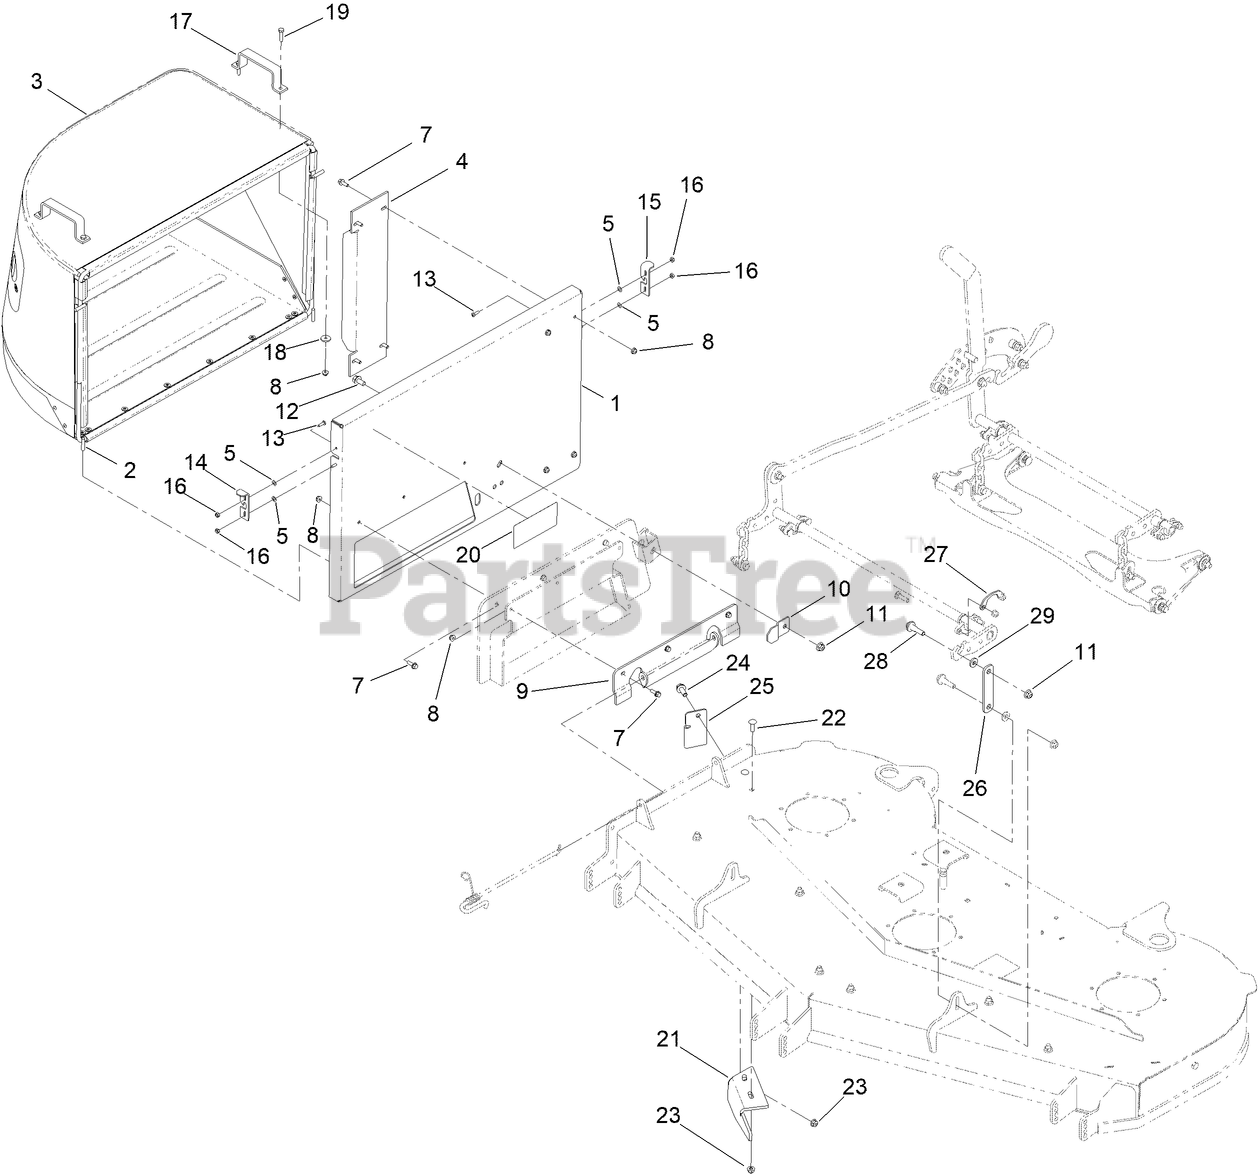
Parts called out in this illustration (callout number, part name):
1	PLATE-BAGGER
2	FRAME-CATCHER
3	PAN AND CATCHER
4	BRACKET-SUPPORT, BAGGER
5	WASHER-SPRING
7	SCREW-HHF
8	NUT-HF
9	BRACKET,BAGGER MOUNTING
10	CLAMP - BAGGER
11	NUT-HF, NI
12	SCREW-HHF
13	SCREW-PPH
14	LATCH-CATCHER, LH
15	LATCH-CATCHER, RH
16	NUT-LOCK, NI
17	HANDLE
18	WASHER
19	SCREW-HH
20	DECAL-WARNING, BAGGER
21	BAFFLE-WELDED, 36/60IN DECKS
21	BAFFLE-WELDED, 48/54IN DECKS
22	SCREW-CARR
22	SCREW-HHF
23	NUT-HF, NI
24	SCREW-HHF
24	SCREW-HSBH
25	GUARD-BAGGER
26	PLATE-LINK, BAGGER
27	PLATE-STOP
28	BOLT-SHOULDER
29	SPACER-HUB, BLOWER
